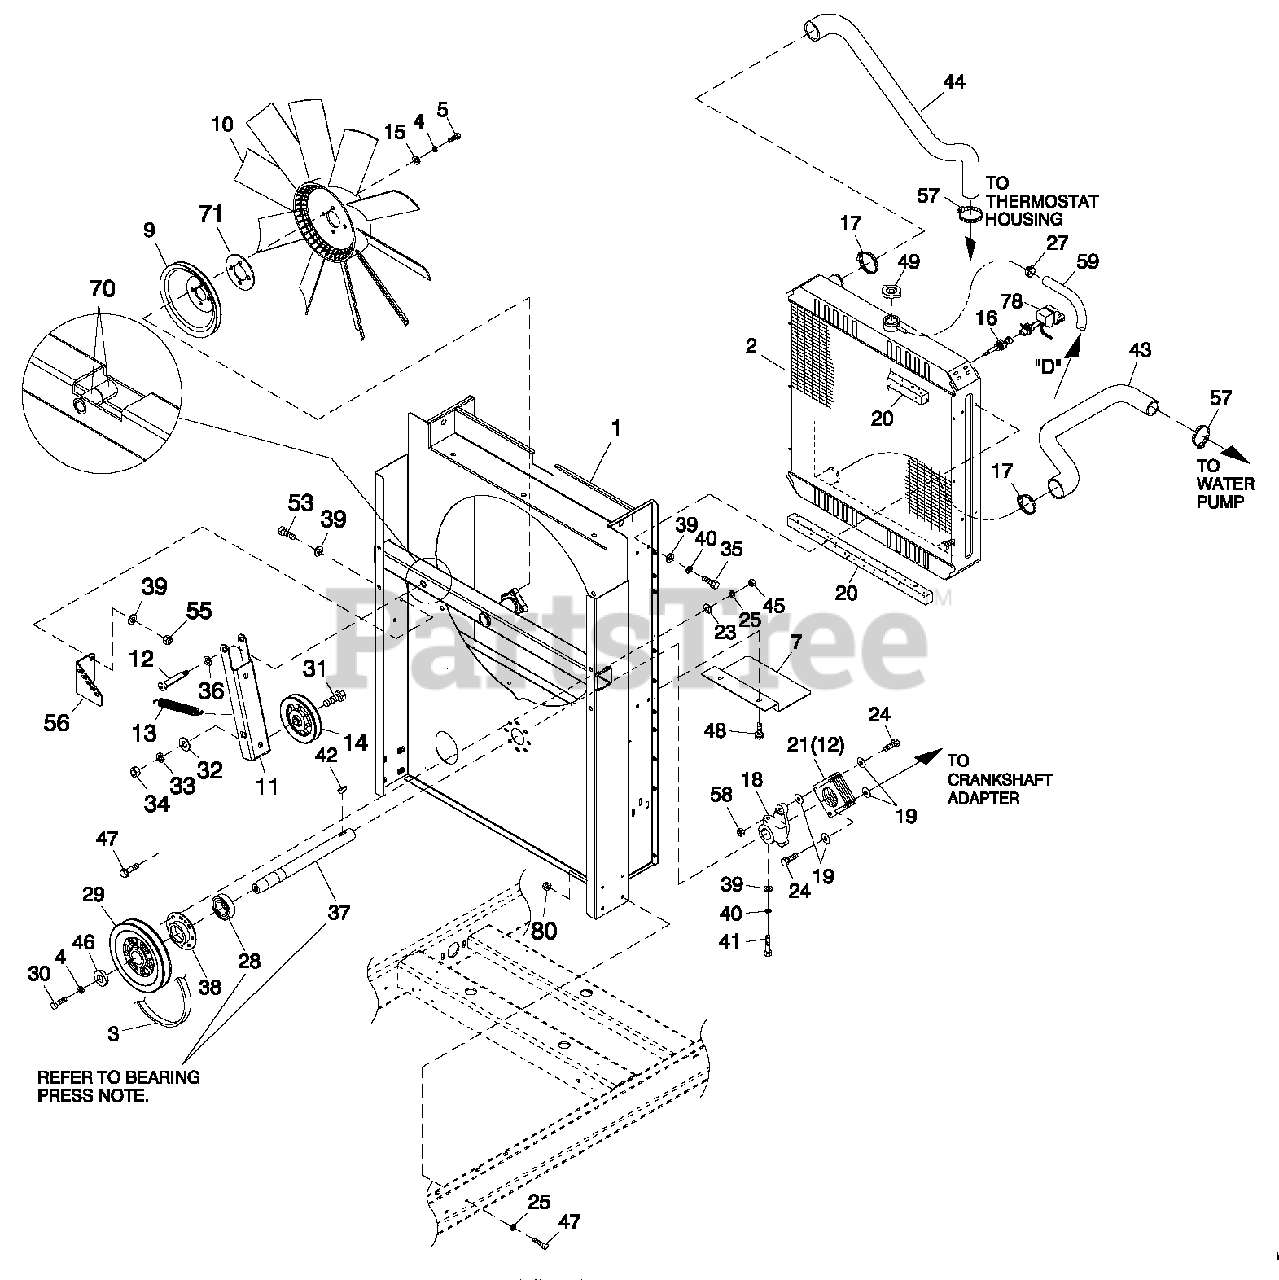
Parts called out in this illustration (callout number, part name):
1	WELDMENT RADIATOR SUPPORT C2
2	RADIATOR 598 X 568 X 49 CPL RH
3	V-BELT 31/ 64" X 57-3/ 8"
4	WASHER LOCK M10
9	PULLEY FAN V-GROOVE 9"
10	FAN COOL 22" D IA 10 BLADE LH
11	ARM BELTTENSIONER
12	SHOULDER BOLT 1/2 X 2-1/4"
13	SPRING TENSION CPL
14	PULLEY V-BELT 4" FLANGED
15	WASHER FLAT 3/8-M10 ZINC
16	PROBE COOLANT LEVEL 3/8 NPTF
17	CLAMP HOSE #28 1.32-2.25
18	HUB FLEX PLATE
19	WASHER FLEX (THIN)
20	TAPE FOAM 1 X 1 (26.75" LG)
21	DISK FLEX
24	SCREW HHC 5/16-24X1.124
25	WASHER LOCK M6-1/4
27	CLAMP HOSE BAND 1/4
28	BEARING #6205 2NSE C3 E SRI2 S
29	PULLEY 5.125" DIA MACHINED
30	SCREW HHC M10-1.5X 30 G8.8
31	SCREW HHC 1/2-13 X 2" G8
32	WASHER FLAT 1/2 ZINC
33	WASHER LOCK 1/2
34	NUT HEX 1/2-13 STEEL
35	SCREW HHFC M8-1.25X20W/M6
36	WASHER NYLON .50 X .87 X .06
37	SHAFT FAN DRIVE
38	RETAINER BEARING
39	WASHER FLAT 5/16-M8ZINC
40	WASHER LOCK M8-5/16
41	SCREW HHC M8-1.25X 45 C8.8
42	KEY WOODRUFF 4 X 19D
43	HOSE LOWER RADIATOR G2
44	HOSE UPPER RADIATOR G2 (USED WITH MANFLD P/N 0G0707)
45	NUT HEX M 6X 1 .0G 8Y E L C H R
46	SPACER .5 X 1.5 X .25 STL/ZINC
47	SCREW HHFC M6-1.0X 20G8.8
48	SCREW THF M6-1 X 16 N WA Z/JS
49	CAP RADIATOR 13 PSI
53	SCREW HHC M8-1.25X20 C8.8
55	NUT HEX LOCK M8-1.25 NY INS
56	BRACKET TENSIONER SPRING
57	CLAMP HOSE #24 B1.06-2.00
58	NUT HEX LOCK 5/16-24 NY INS
59	HOSE 9/32 ID (36"LG)
70	BEARING SLEEVE 1 /2 /X 3 /4X 1
71	SPACER CPL COOLING FAN 1/8"
78	ASSY PCB LCL SENSOR (USE WITH I/N 16, P/N 0H1827 ONLY)
